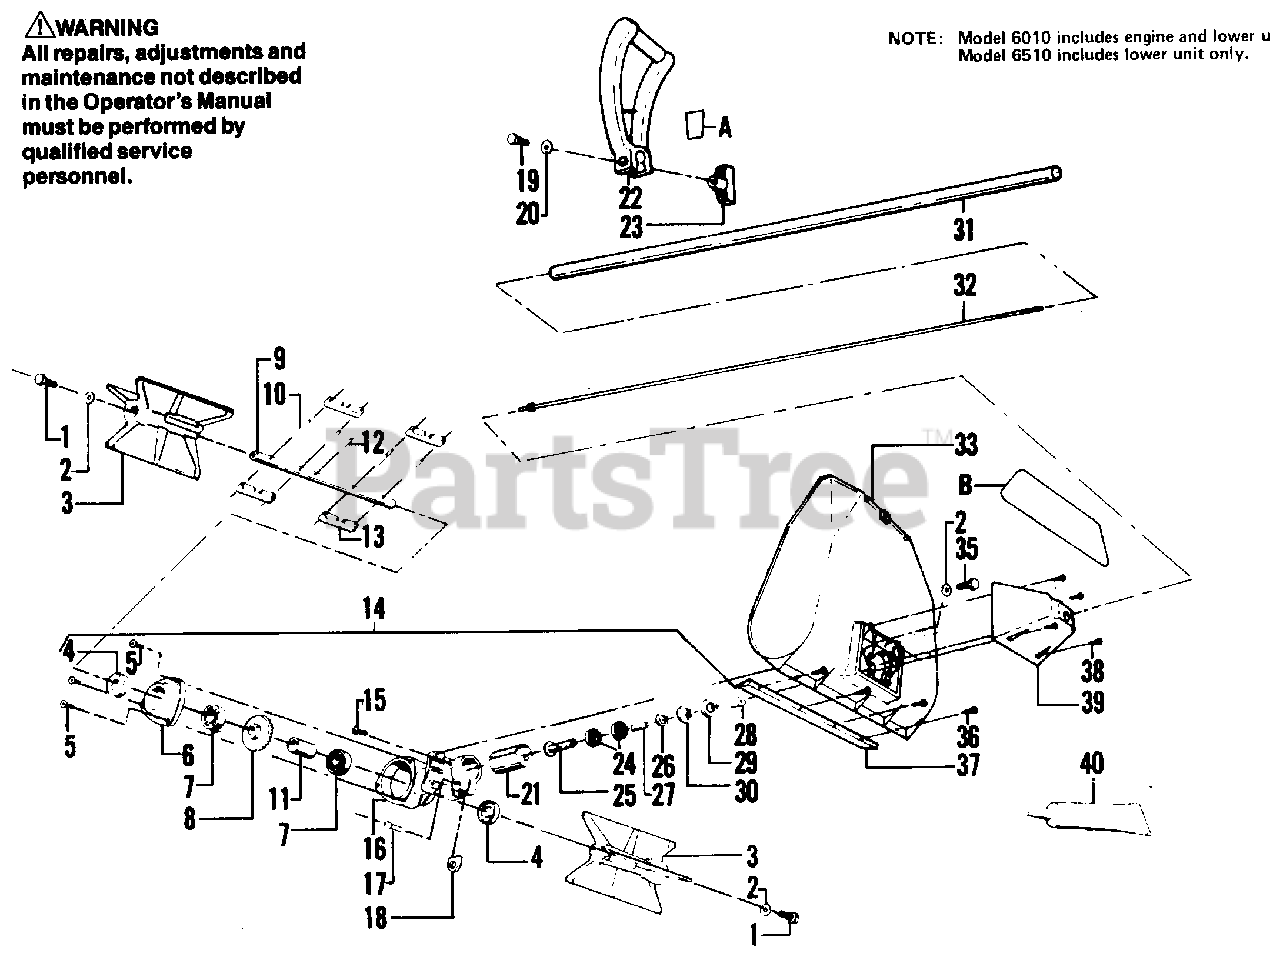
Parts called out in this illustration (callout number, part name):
1	Screw - Impeller - 1/4 - 20 x 1/2 - Hex Cap
2	Washer - Impeller & Gear Box Mtg.
3	Impeller
4	Oil Seal - Double Lip
5	Screw - Gear Housing
6	Gear Housing Cover
7	Bearing - Shaft
8	Gear - Spiral Bevel
9	Output Shaft
10	Pin - Spiral - Brace
11	Collar - Shaft
12	Pin Spiral - Gear
13	Brace - Impeller
14	Gear Box Ass'y (Inc. #4 - 8, 11, 15 - 18 & 21 - 30)
15	Screw - Index 10 - 24 x 7/16 Pan Hd.
16	Gear Housing
17	Screw - Pinch Clamp - 1/4 - 20 x 3/4 - Hex Socket Head
18	Washer - Fiber Filler
19	Screw - Assist Handle
20	Washer - Assist Handle
21	Sleeve - Housing
22	Assist Hande
23	Knob - Assist Handle
24	Bearing - Pinion
25	Pinion Gear - Spiral Bevel
26	Retaining Ring - Pinion
27	Collar Pinion
28	Plug - Grease
29	Oil Seal - Single Lip
30	Retaining Ring - Bearing
31	Drive Shaft Housing (Inc. #32)
32	Drive Shaft
33	Housing - Impeller
35	Screw - Gear Box Mounting
36	Screw - Scraper Bar - 8 - 12 x 3/4 - Fil. Hd.
37	Scraper Bar
38	Screw - Rear Cover - 8 - 12 x 3/4 - Fil. Hd.
39	Cover - Rear
40	Grease - Optional
B	Decal - Caution and Model
